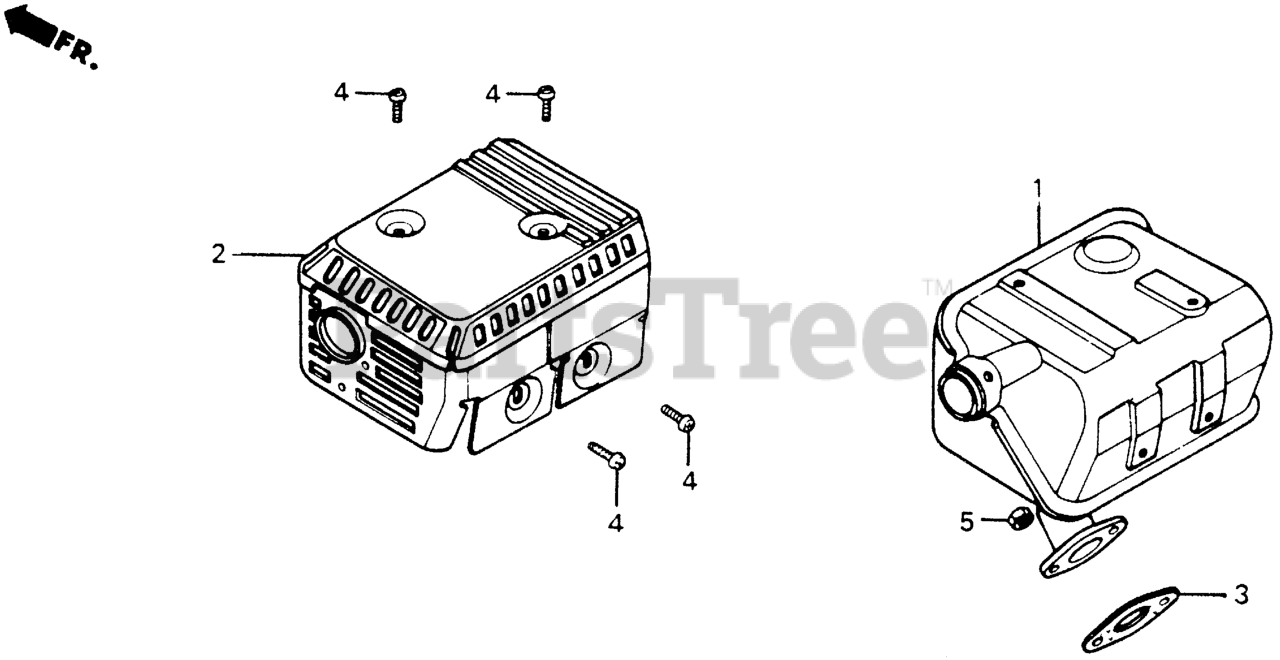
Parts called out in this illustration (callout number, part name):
1	MUFFLER (STD) Use up to Engine SN 1869307.
2	PROTECTOR, MUFFLER (ALUMINIZED)
3	GASKET, MUFFLER
4	SCREW, TAPPING (5X8)
5	NUT, HEX. (8MM)
